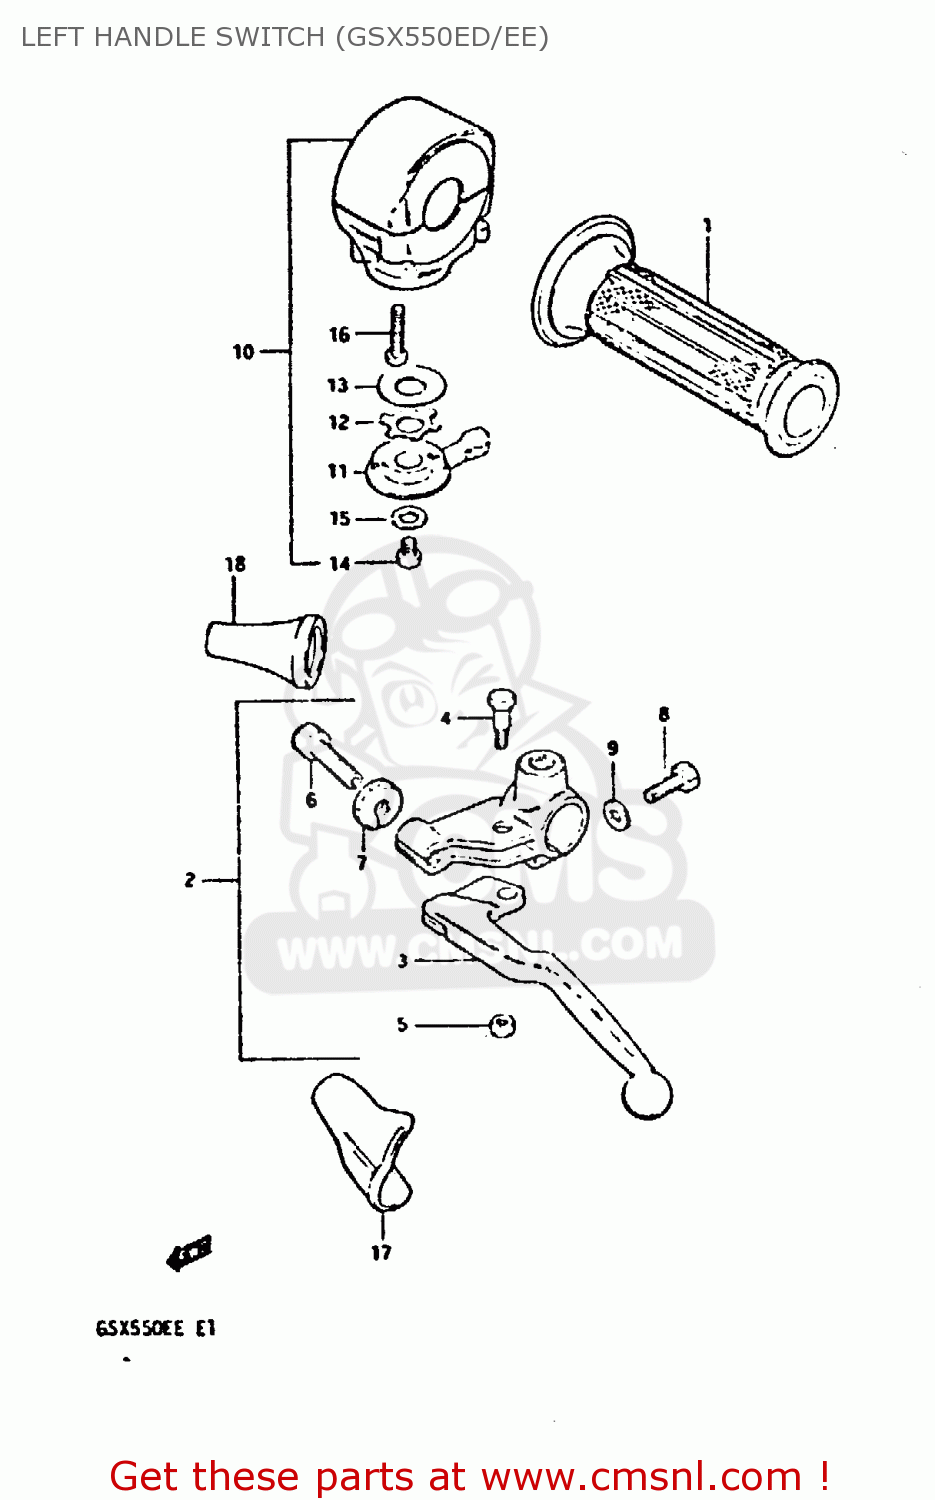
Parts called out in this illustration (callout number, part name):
1	GRIP,L
2	LEVER ASSEMBLY,CLUTCH
3	LEVER,CLUTCH
4	BOLT,LEVER PIVOT
5	NUT 6MM
6	ADJUSTER,CABLE
7	NUT,CABLE ADJUSTER LOCK
8	BOLT,CLUTCH LEVER HOLDER
9	WASHER
10	SWITCH ASSY, HANDLE LH
11	LEVER,STARTER
12	WASHER
13	WASHER
14	SCREW
15	WASHER 6MM
16	SCREW
17	COVER,CLUTCH LEVER
18	BOOT,CLUTCH CABLE
